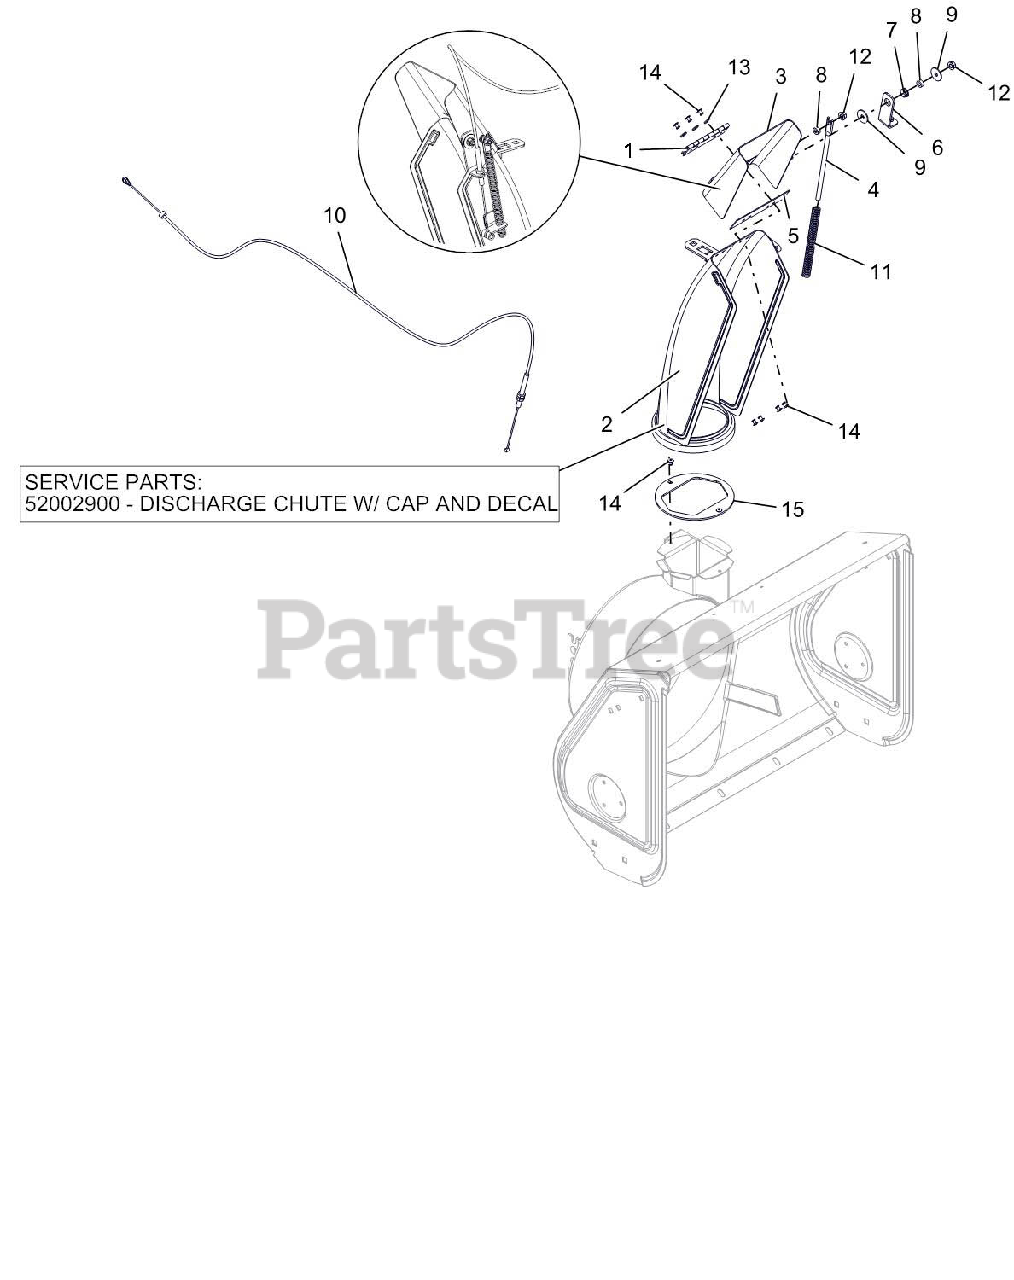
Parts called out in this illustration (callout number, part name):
2	CHUTE, DISCHARGE W/REM.CAP,DEC
2	CHUTE, COMPACT-TALL W/REMOTE
3	CAP,REMOTE - COMPACT (W/DECAL)
4	ROD, DEFLECTOR CAP
5	CAP SEAL 5.25
6	BRACKET, CABLE ANCHOR
7	BUSHING, POLYLINER-.50 SNAPIN
8	BSHG-SLV .265X.500X.219
9	WSHR-FL-STL .281X1.000X.063
10	CABLE, DEFLECTOR - COMPACT
11	SG-COMP .08X.40X6.50 14#/IN
12	@NUT-LK-TOP-FLG .25-20 YWZC
13	WSHR-FL-STL .196X.500X.06 YZ
14	RVT-POP .187 YZ
15	BAFFLE, COMPACT DISCHARGE
